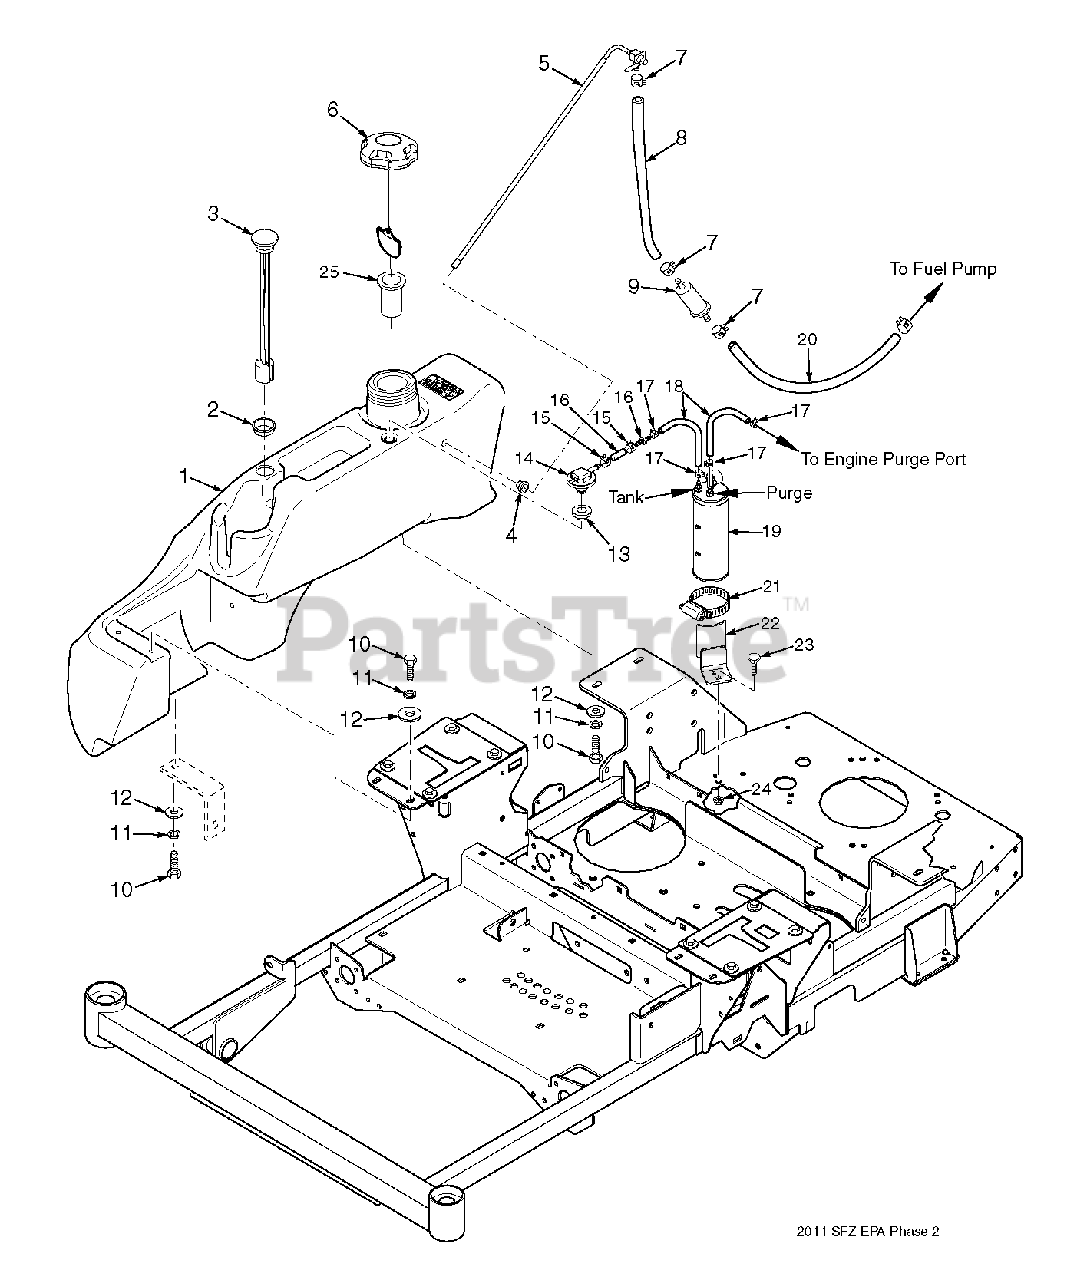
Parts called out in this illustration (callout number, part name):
1	Fuel Tank Assembly
2	Grommet
3	Fuel Gauge Assembly
4	Bushing, .56 Dia. Viton
5	Fuel Tube Assembly
6	Fuel Cap, Tethered
7	Clamp, Fuel Hose 1/4"
8	Fuel Hose, 1/4" Non-Perm
9	Fuel Filter
10	Bolt, Hex Head 5/16-18 x 3/4"
11	Lockwasher, 5/16" Spring
12	Flatwasher, 5/16-.375 x .875 x .083
13	Grommet, Viton
14	Remote Vent
15	Clamp, Fuel Hose 7/32"
16	Hose, 1/4" Vapor Recovery
17	Clamp, Vapor Recovery Hose
18	Hose, 3/16"
19	Carbon Canister
20	Fuel Hose
21	Clamp, Hose
22	Bracket Weldment
23	Bolt, Carriage 5/16-18 x 3/4"
24	Nut, Serrated Flange 5/16-18
25	Tube, Fuel Tank Insert
26	Mender, 1/4 x 3/16 w/0.02 Hole
